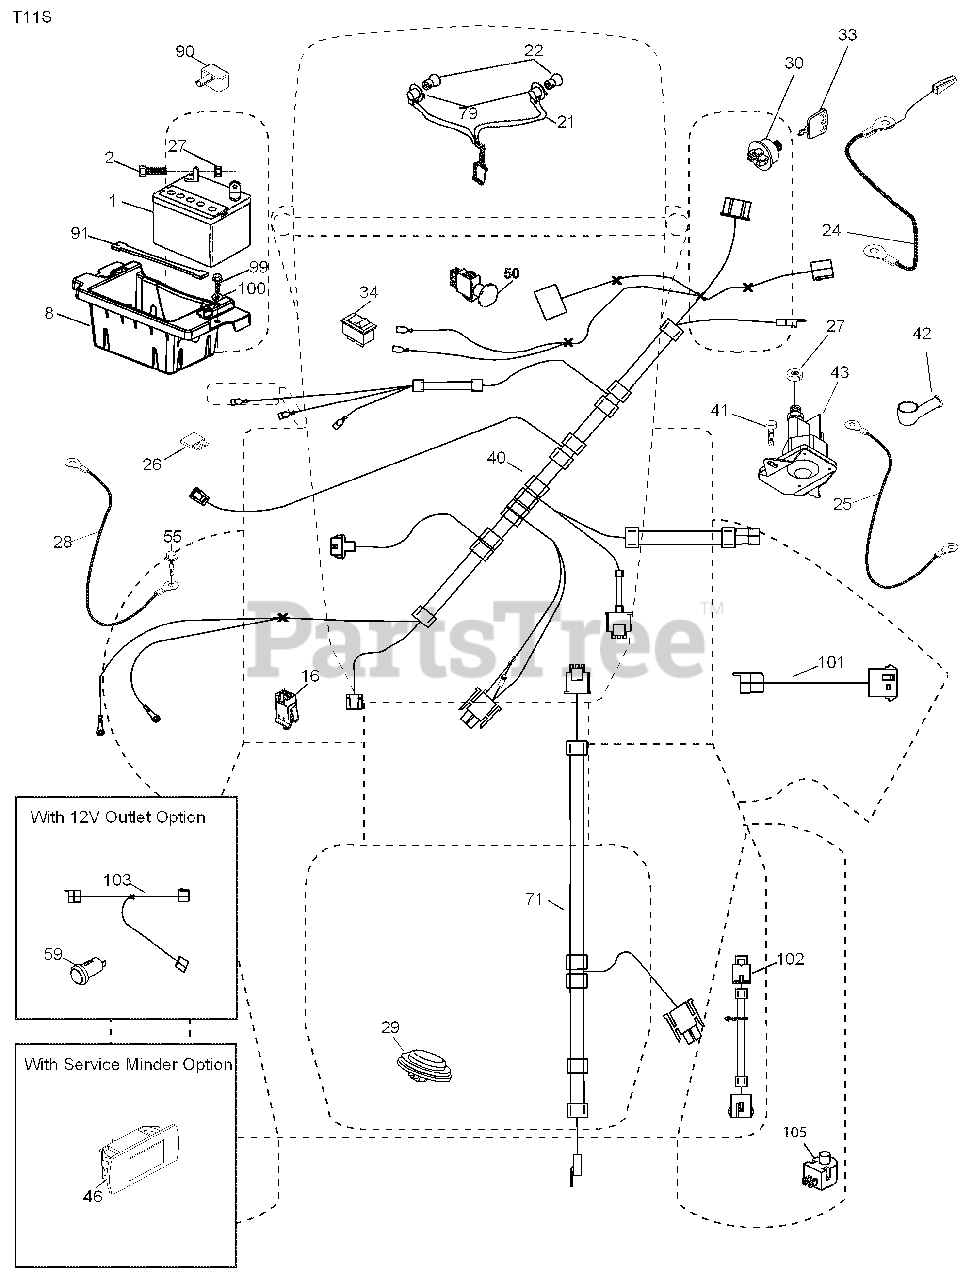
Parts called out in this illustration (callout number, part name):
1	Battery
2	Bolt Hex Hd 1/4-20 unc x 3/4
8	Battery Box
16	Switch Interlock
21	Harness Socket Light
22	Bulb, Light # 1156
24	Cable Battery
25	Cable Starter
27	Nut Keps Hex 1/4-20 unc
28	Cable Ground 21" Blk 6 Ga.
29	Switch Seat
30	Switch Ign
33	Key / Chain
34	Switch Light/Reset
40	Harness Ign. Dash
41	Screw Thd Cut 1/4-20 x 1/2
42	Cover Terminal Red
43	Solenoid
46	Gauge Hourmeter
50	Switch PTO
55	Screw Thdrol 5/1618 x 3/4
59	Outlet 12-Volt
71	Harness Ign
79	Socket Asm Bulb Twistlock
90	Cover Terminal Battery
91	Strap Battery
99	Screw Hexwsh Thdrol 1/4-20 x 3/4
100	Washer 9/32 x 7/8 x 16 Ga.
101	Pigtail MATNLK
102	Harness Pigtail K46 Tex ROS
103	Harness Pigtail 12V Outlet
105	Switch Reverse TT Pedal
